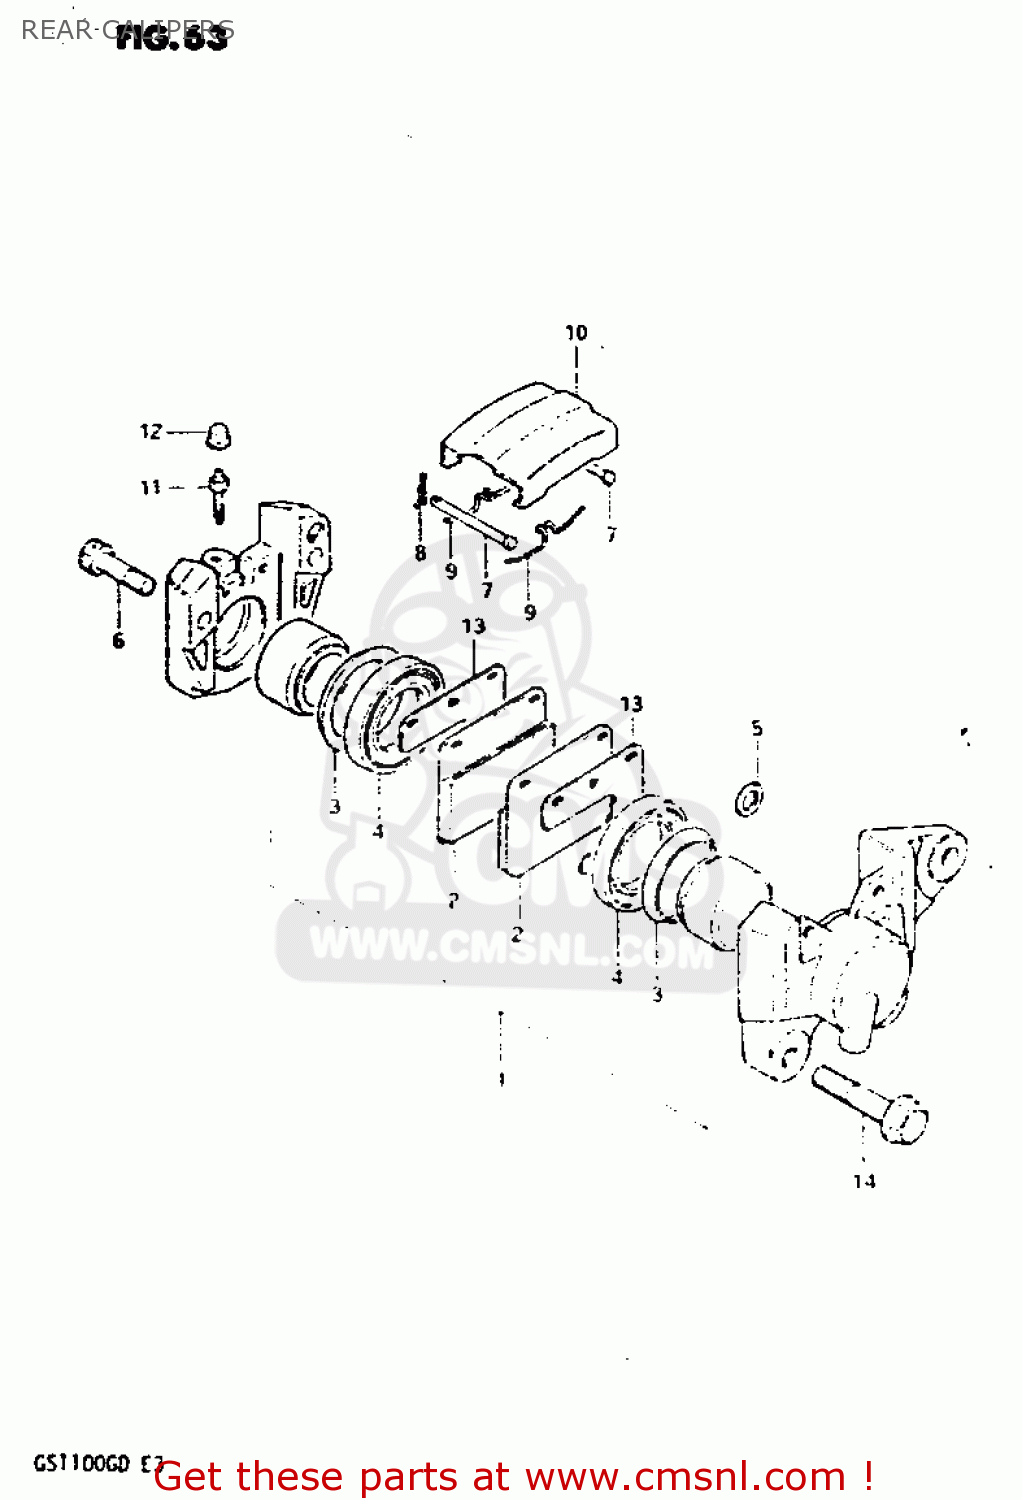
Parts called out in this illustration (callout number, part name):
1	PISTON SET
2	PAD,BRAKE (MCA)
3	SEAL,PISTON
4	BOOT,PISTON
5	SEAL,JOINT
6	BOLT,CALIPER HOUSING
7	PIN,PAD
8	CLIP,PAD PIN
9	SPRING
10	COVER,DUST
11	BLEEDER
12	CAP,BREATHER
13	SHIM,RR CALIPER
14	BOLT
